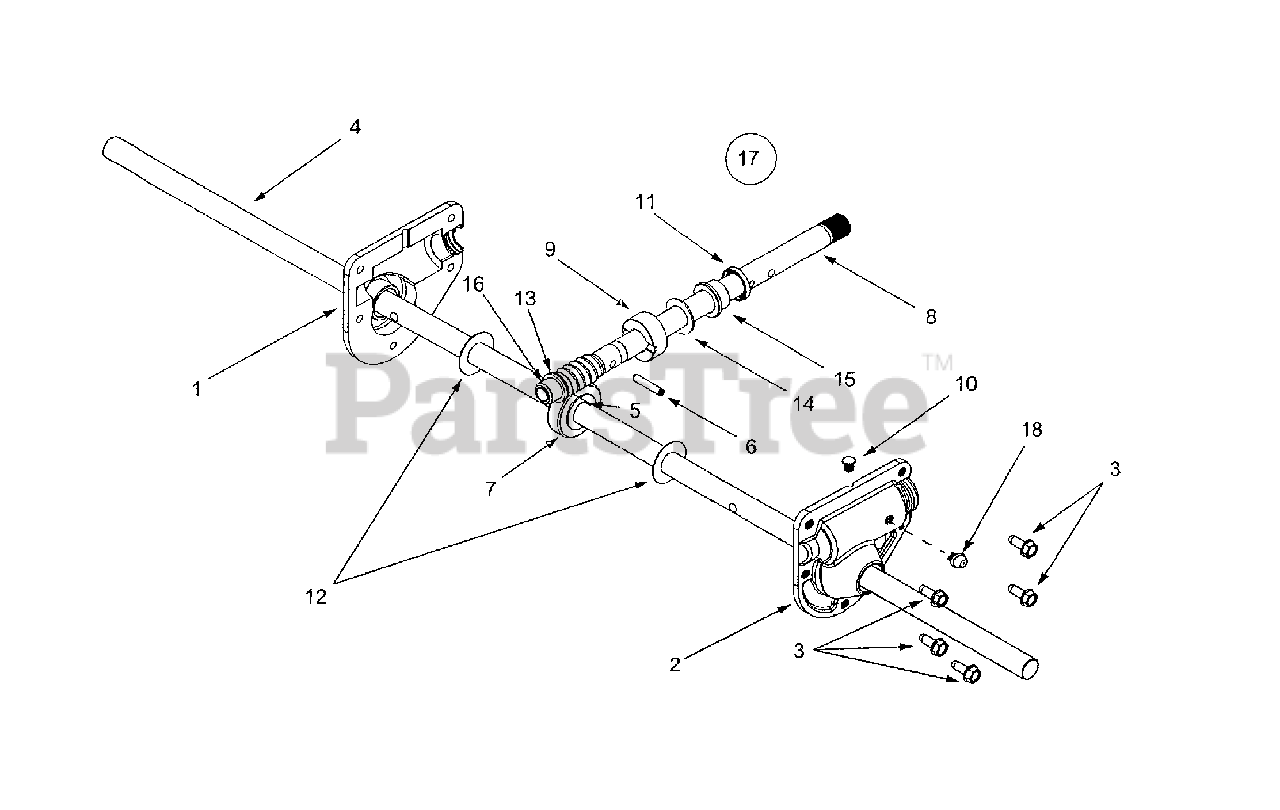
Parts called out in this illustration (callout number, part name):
1	RH Housing
2	LH Housing w/Fitting
3	Self Tapping Screw, 1/4-20 x .75
4	Spiral Axle, 24"
5	Hi-Pro Key, 3/16 x 5/8
6	Spring Spiral Pin, .25 x 1.25
7	Worm Gear, 20-tooth
8	Worm Shaft
9	Thrust Collar
10	Grease Plug
11	Grease Seal
12	Flat Washer, .76 x 1.5 x .030
13	Flat Washer, .508 x 1.0 x .020
14	Flat Washer, .76 x 1.5 x .060
15	Flange Bearing, .75 x 1.0 x .59
16	Flange Bearing, .503 ID x .75 OD
17	Gear Assy Complete, 24"
18	Grease Fitting, 3/16" Drive
